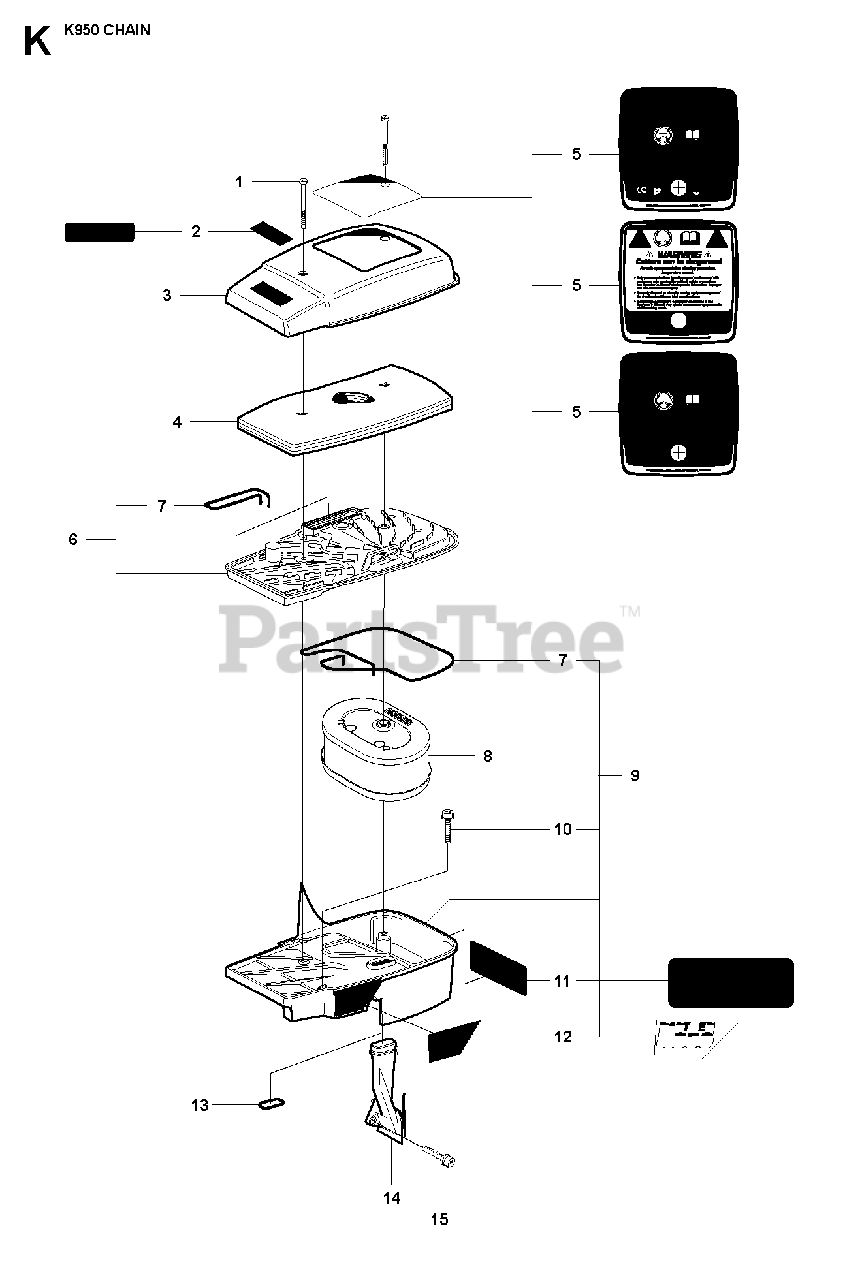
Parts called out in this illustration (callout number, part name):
3	COVER
5	LABELEPA USA
5	LABELEPA Canada
6	FILTER BOTTOMIncl. 7
9	CYLINDER COVER ASSYIncl. 7, 10, 11, 12
10	SCREW IHSCFM
12	LABEL
15	SCREW IHSCFM
